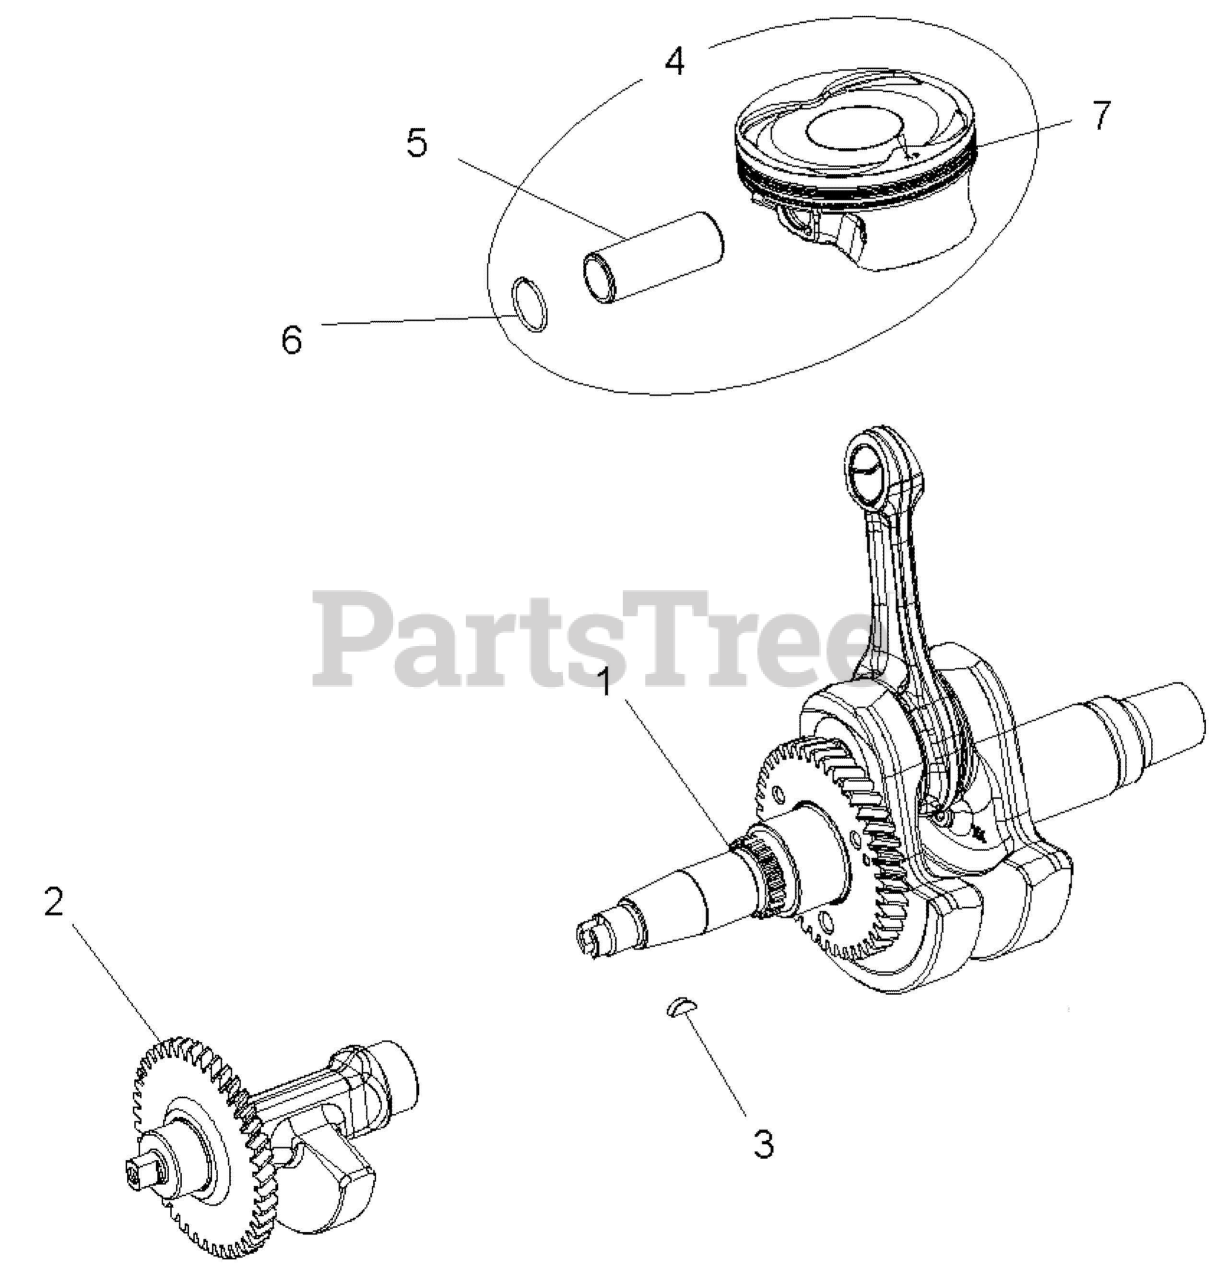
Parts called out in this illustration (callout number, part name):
1	ASM, CRANKSHAFT
2	ASM-BALANCE SHAFT
3	KEY,WOODRUFF
4	KIT-PISTON 99MM
5	PIN-PISTON,22X12.8X56.6MM
6	C-CLIP,RND (2)
7	KIT-RING,STD
